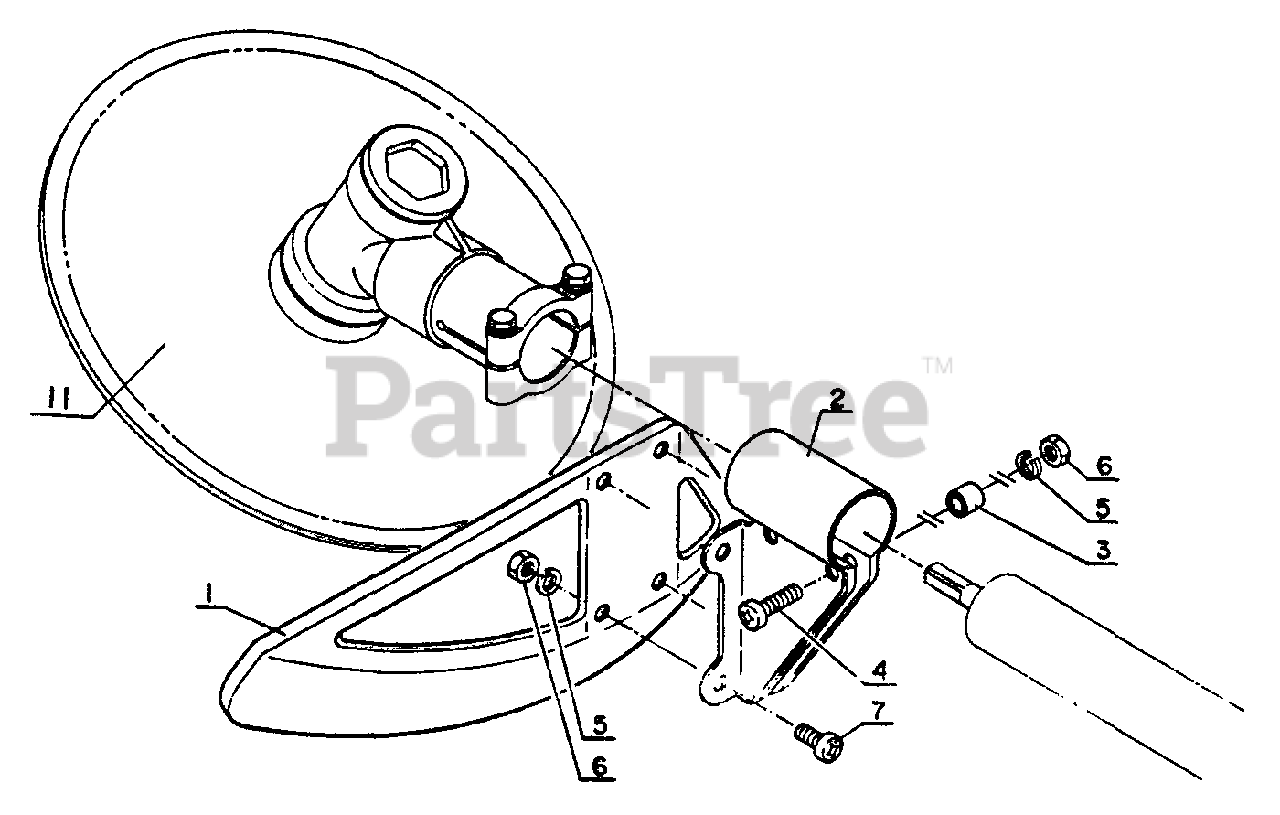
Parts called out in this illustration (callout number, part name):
1	SHIELD, DEBRIS
2	BRACKET, SHIELD
4	SCREW - 5X18
5	LOCKWASHER - 5
7	SCREW - 5X8
11	SAW, CIRCULAR
